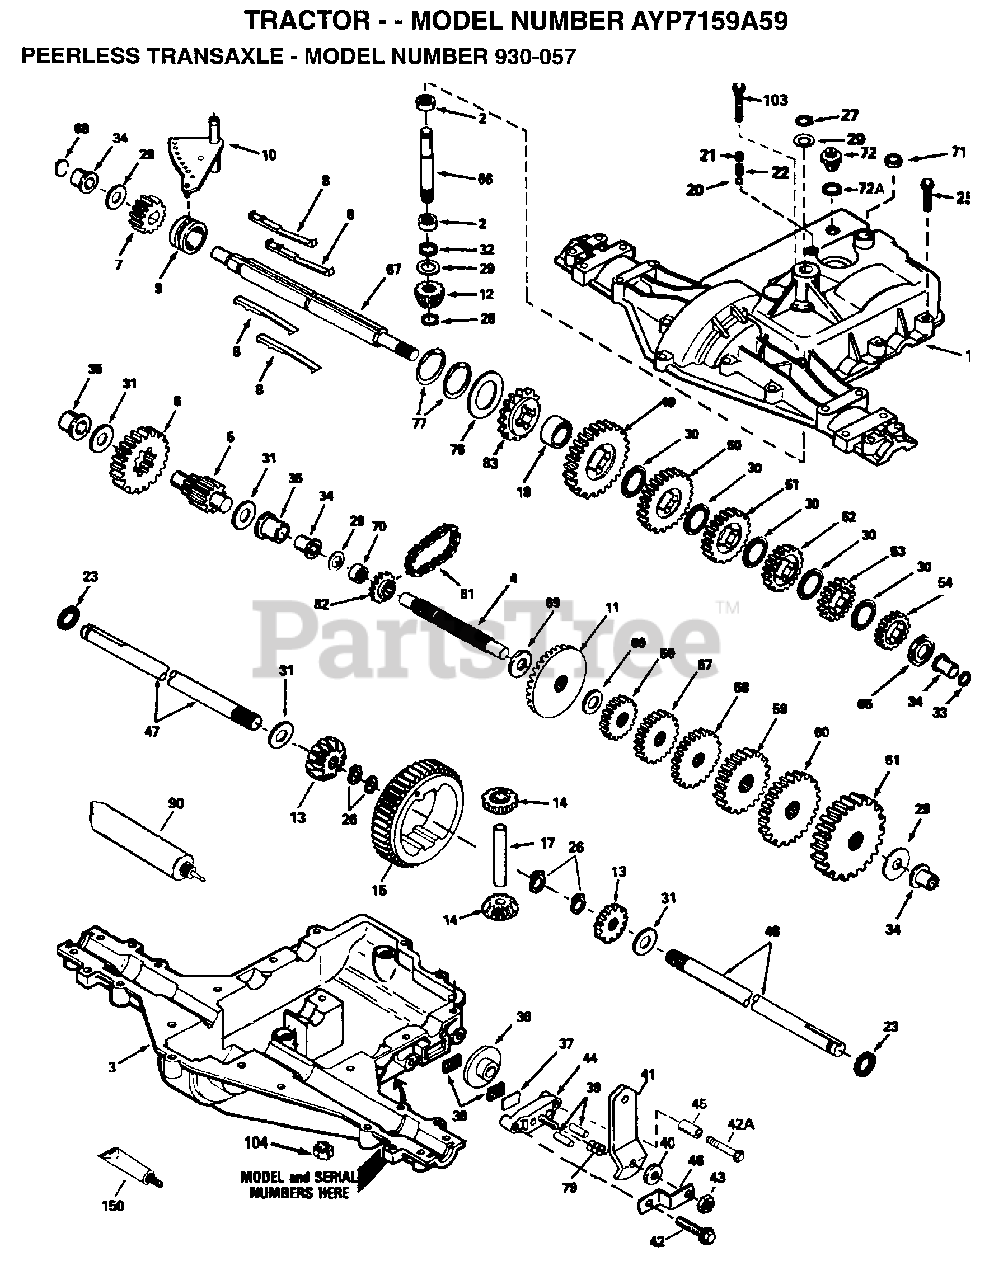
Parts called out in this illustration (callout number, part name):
1	TRANSAXLE COVER
2	BEARING, NEEDLE
3	TRANSAXLE CASE
4	SHAFT, COUNTER
5	OUTPUT SHAFT AND PINION
6	GEAR, OUTPUT
7	GEAR, SPUR, 15 TEETH
9	COLLAR, SHIFTER
10	ROD & FORK ASSY, SHIFT
11	GEAR, BEVEL, 42 TEETH
12	BEVEL PINION, INPUT
13	GEAR, BEVEL
14	GEAR, BEVEL, PINION
18	SPACER, NEUTRAL
20	BALL STEEL, 5/16" DIA.
21	SCREW, 3/8-16 X 3/8"
25	SCREW, 1/4-20 X 1-1/4
26	RING RETAINER
27	RING, RETAINER
28	RETAINING RING
29	WASHER THRUST
30	WASHER THRUST
33	SEAL, SQUARE CUT
34	BUSHING, FLANGED
35	BUSHING, FLANGED
36	DISK, BRAKE
37	PLATE BRAKE PAD
41	BRAKE LEVER
42	SCREW, 1/4-20 X 1-1/4
42A	SCREW, 1/4-20 X 2-1/4
43	LOCKNUT 5/16-24
44	HOLDER BRAKE PAD
46	BRKT BRAKE LEVER
49	GEAR, SPUR, 37 TEETH
50	GEAR, SPUR, 35 TEETH
51	GEAR, SPUR, 30 TEETH
52	GEAR, SPUR, 25 TEETH
53	GEAR, SPUR, 22 TEETH
54	GEAR, SPUR, 19T
56	GEAR, SPUR, 12 TEETH
57	GEAR, SPUR, 15 TEETH
58	GEAR, SPUR, 20 TEETH
59	GEAR, SPUR, 25 TEETH
60	GEAR, SPUR, 28 TEETH
61	GEAR, SPUR, 31 TEETH
65	WASHER, THRUST
66	SHAFT, INPUT
67	SHAFT, BRAKE, 4 KEYED
69	WASHER THRUST
71	SEAL SQUARE CUT
72	THREADED PLUG 9/16-18
76	WASHER, THRUST
77	INVERTED RETAINING RING
81	CHAIN, ROLLER
82	SPROCKET 9T
83	SPROCKET 18T (REV)
90	GREASE BENTONITE, 32 OZ.
150	GASKET ELIMINATOR
